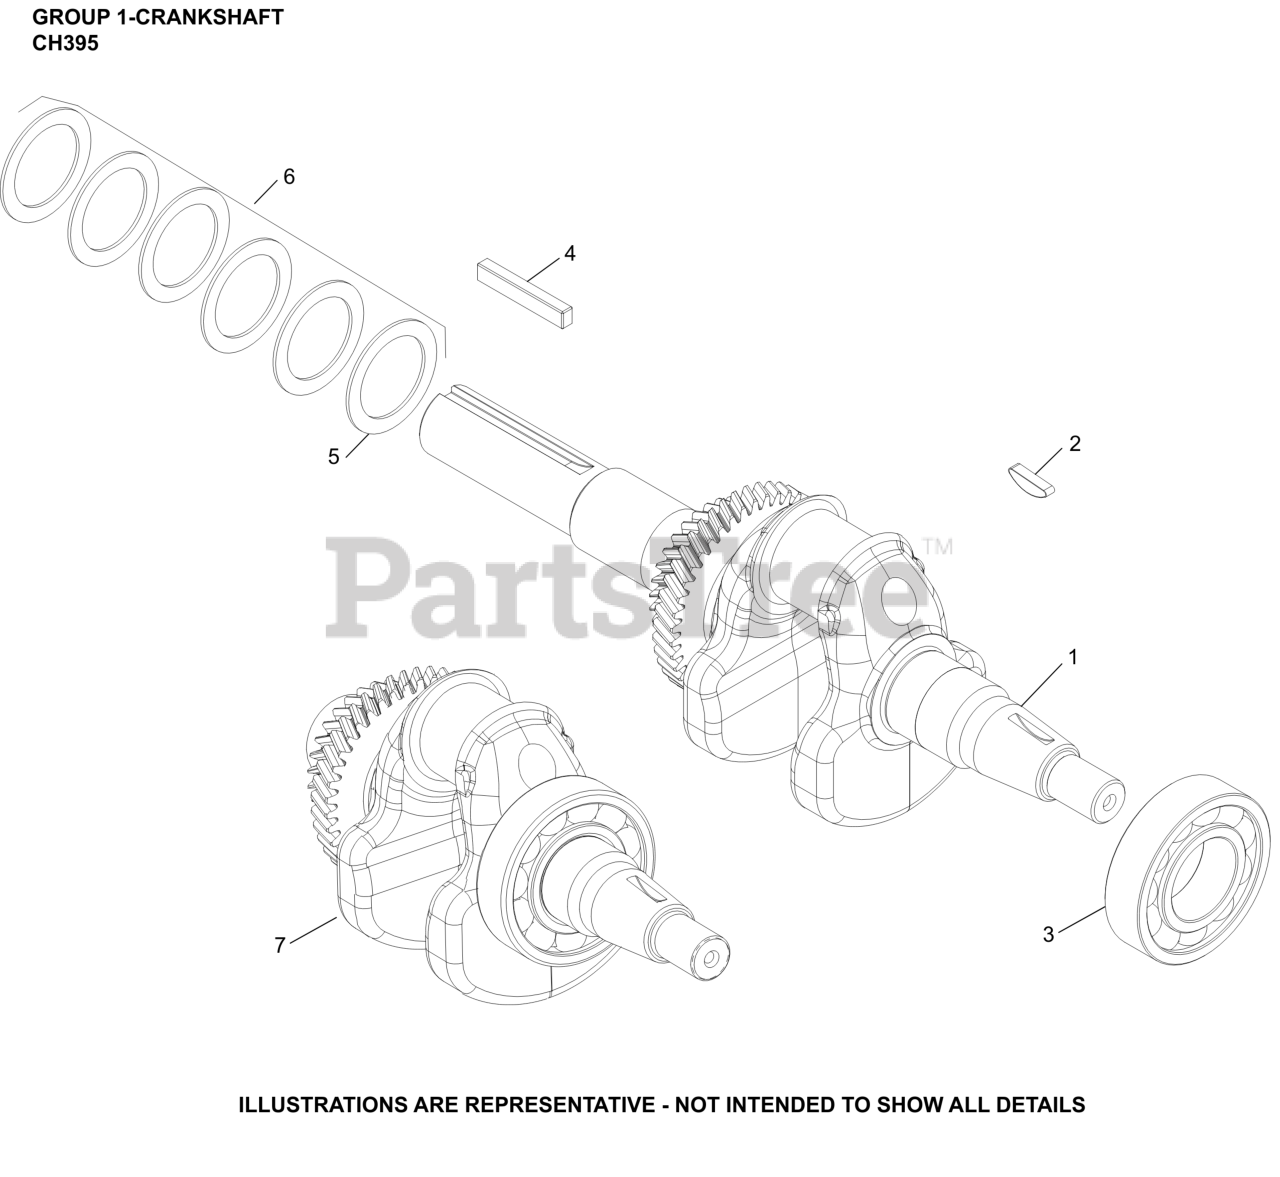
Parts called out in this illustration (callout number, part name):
1	CRANKSHAFT ASSEMBLY
2	KEY, FLYWHEEL
6	KIT, SHIMS
